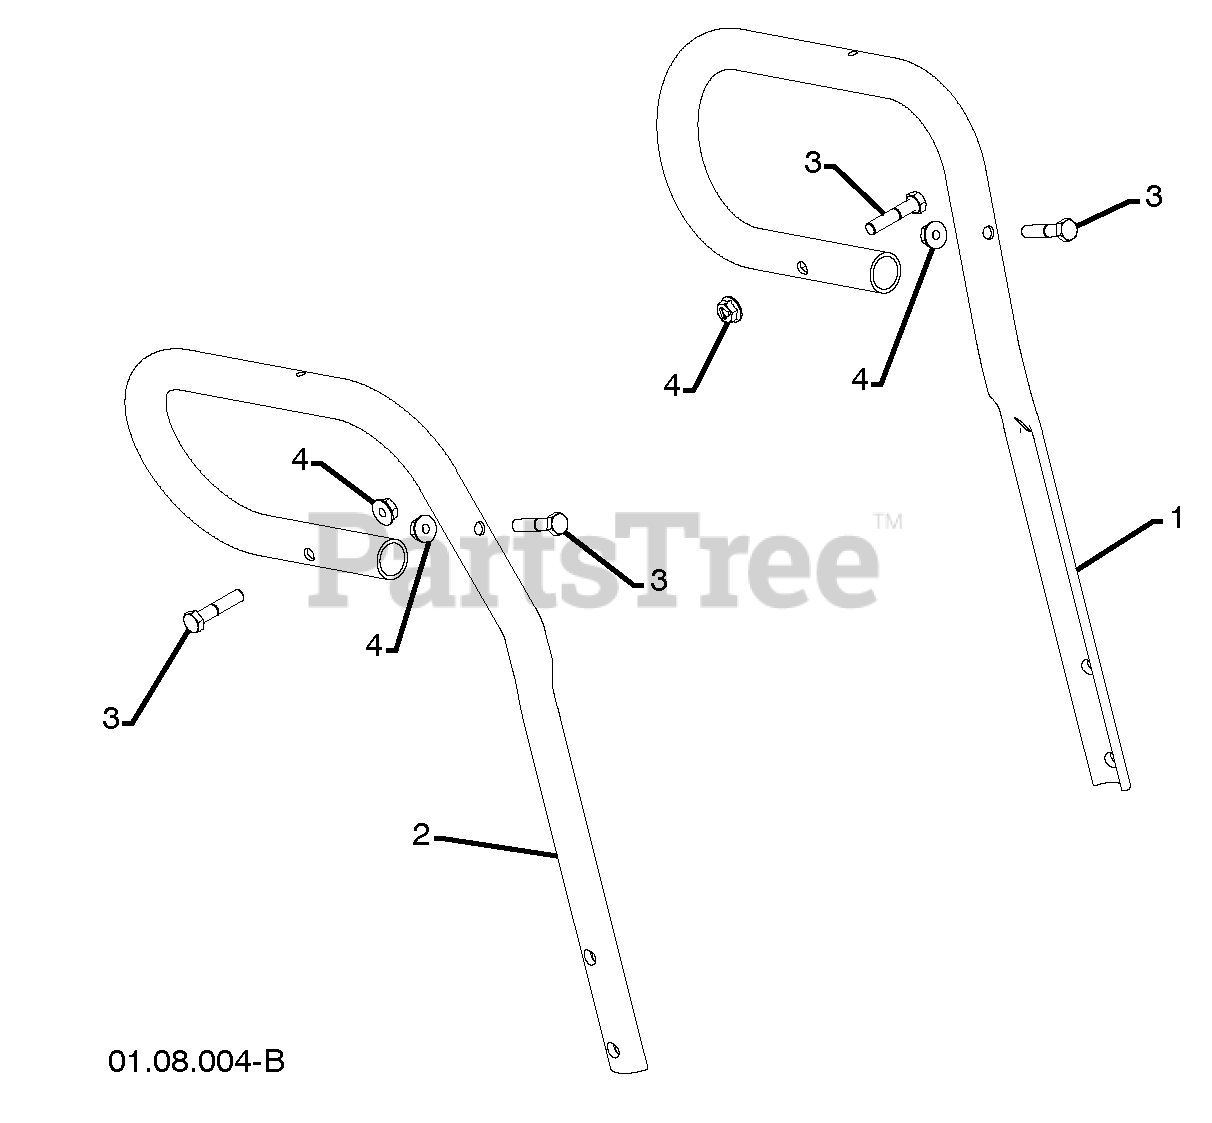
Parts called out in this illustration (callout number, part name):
1	LOOP HANDLE LH
2	LOOP HANDLE RH
3	SCREW 5/16-18 X 1.50
4	NUT 5/16-18
